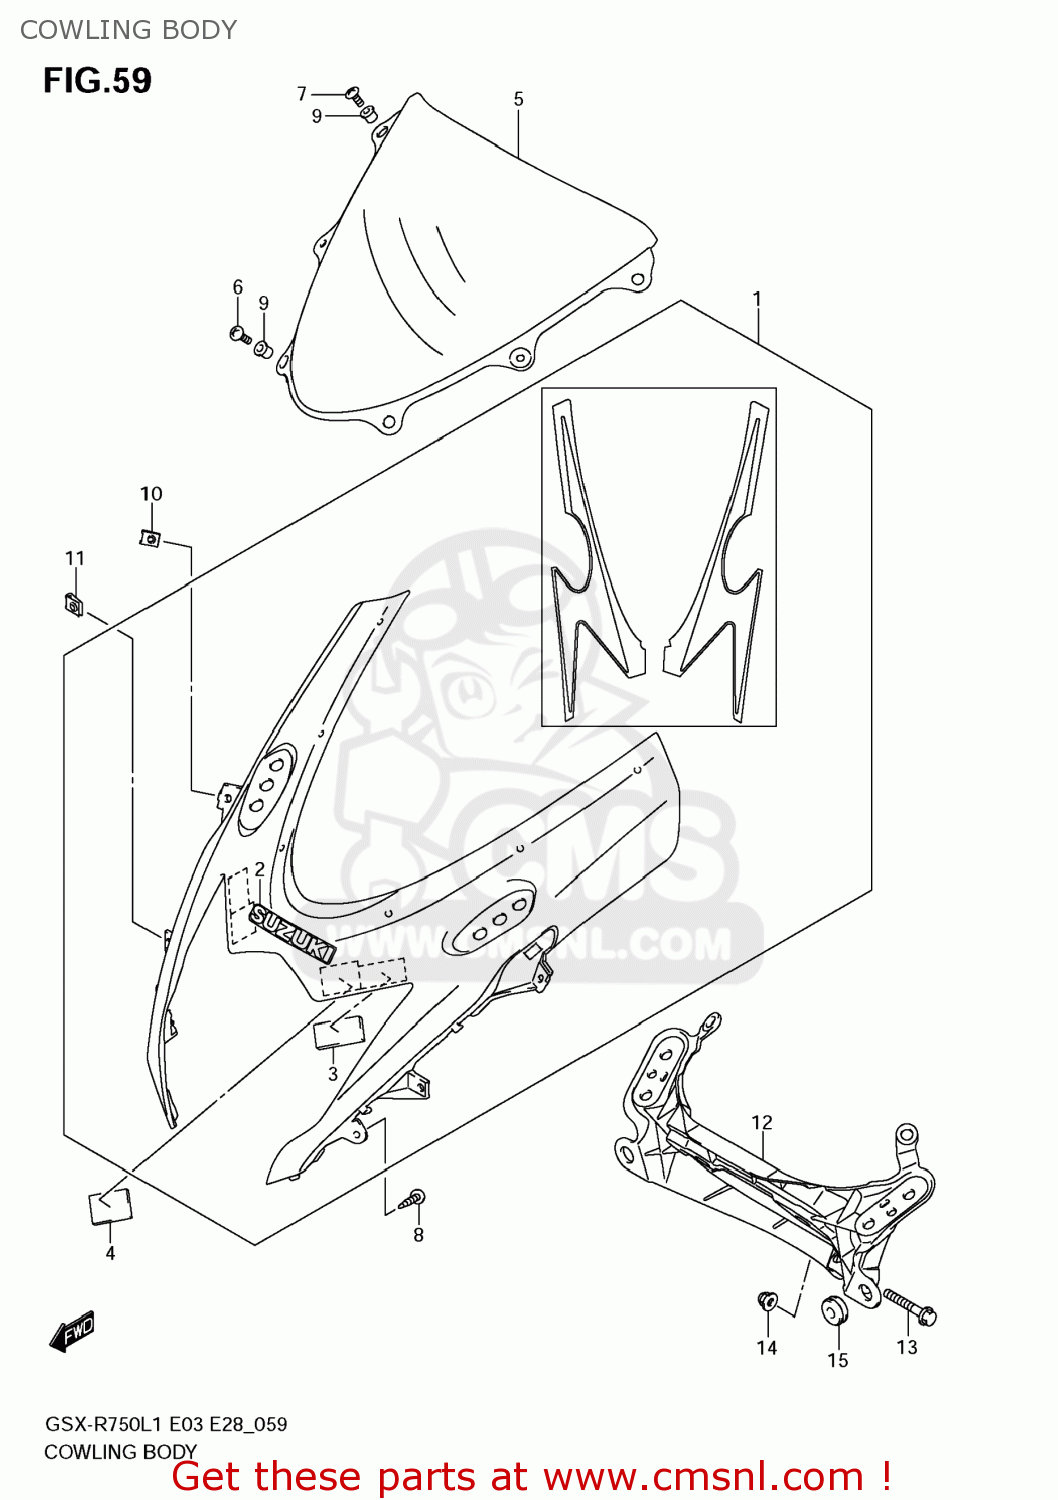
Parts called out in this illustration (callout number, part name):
1	COWLING,BODY(BLUE)
2	EMBLEM(GRAY)
3	CUSHION,BODY COWLING
4	FASTENER
5	WINDSCREEN
6	SCREW(5X18)
7	SCREW(5X15)
8	SCREW
9	NUT
10	NUT
11	NUT
12	BRACE,COWLING
13	BOLT(8X45)
14	NUT
15	CUSHION
